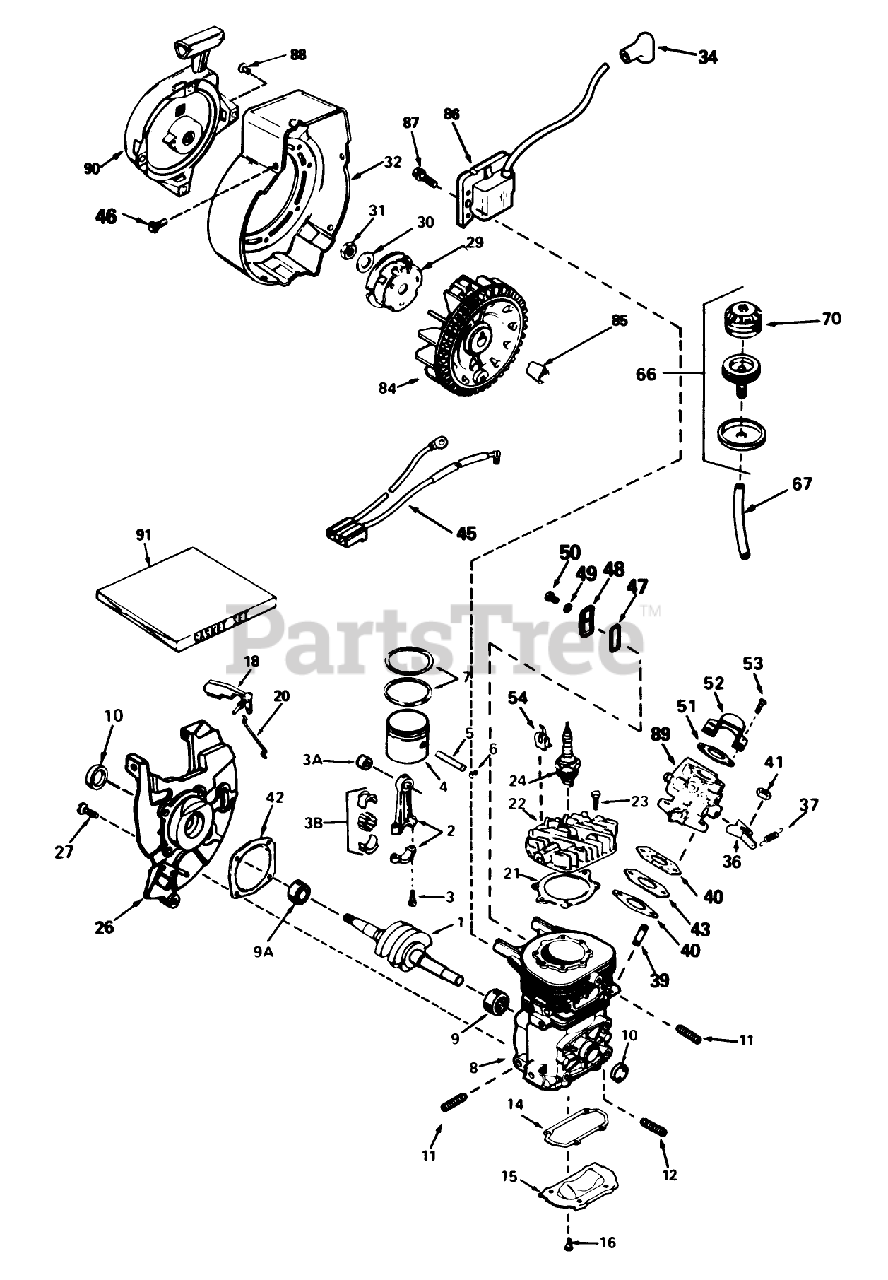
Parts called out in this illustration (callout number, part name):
1	Crankshaft
2	Rod Assy.-Connecting (Incl. Ref. #3, 3A 3B)
3	Bolt-Rod, Connecting
3A	Bearing-Cartridge
3B	Needle Bearing and Liner Set (37 Needles)
4	Piston
5	Pin-Piston
6	Ring-Retaning
7	Ring Set
8	Block Assy.-Cylinder (Order short block if replacement is required.)
9	Bearing-Cartridge
9A	Bearing-Ball
10	Seal-Oil
14	Cover
15	Plate-Cover
16	Screw (T-25, 10-24 x 1/2)
18	Vane-Air
20	Link-Governor
21	Gasket, Head
22	Head-Cylinder
23	Screw (T-30, 1/4-20 x 3/4)
24	Spark Plug-Resistor (R C J 8Y)
26	Base Assy.-Blower Housing (Incl. Ref. #10)
27	Screw (1/4-20x19/32)
29	Cup-Starter
30	Washer-Belleville
31	Nut-Flywheel
32	Housing-Blower
34	Cover-Spark Plug
36	Lever-Adjusting, Rpm
37	Spring-Governor
40	Gasket-Carburetor
41	Locknut
42	Gasket, Shroud Base
43	Spacer
45	Harness-Wire
46	Screw-Hex, Hd.
47	Gasket-Cover
48	Comp. Release Cover
49	Washer
50	Screw (T-25, 10-24 x 1/2)
51	Gasket
52	Baffle-Carburetor
53	Screw
66	Primer Assy.
67	Line-Primer
70	Bulb-Primer
84	Flywheel
85	Blade (20 inch)
86	Solid State
87	Screw
88	Rivet-Pop (3/16" Dia.) (Can be purchased locally)
89	Carburetor (Incl. Ref. #40)
90	Starter-Rewind
91	Gasket Set
